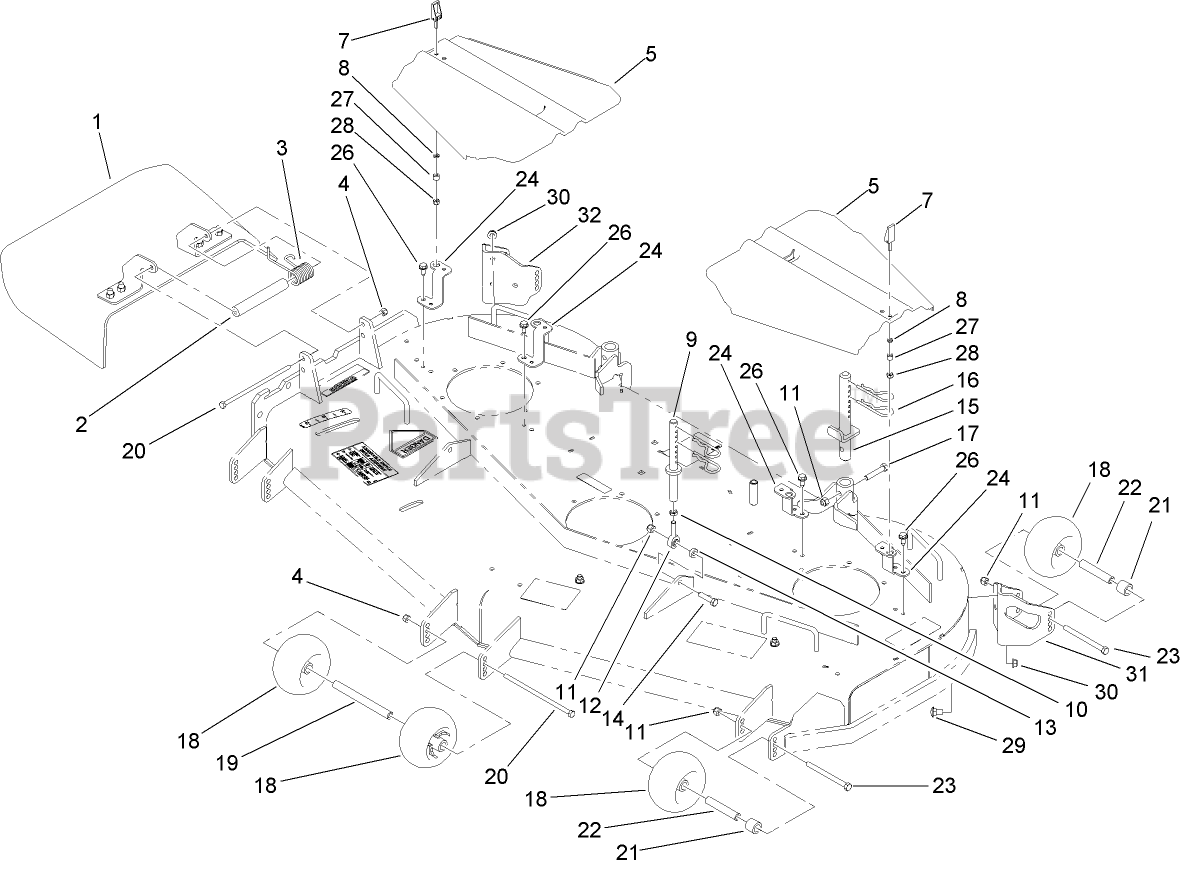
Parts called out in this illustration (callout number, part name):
1	DEFLECTOR ASM
2	SPACER
3	SPRING-TORSION
4	NUT-LOCK, NI
5	COVER-BELT
7	HANDLE-LATCH, SWELL
8	WASHER
9	FRONT PIN ASM
10	NUT-HJ
11	NUT-LOCK, NI
12	BALLJOINT
13	SPACER
14	SCREW-HH
15	REAR PIN ASM
16	PIN-HAIR
17	SCREW-HH
18	ROLLER-SCALP, ANTI
19	SPACER-WHEEL
20	SCREW-HH
21	TUBE-SPACER
22	TUBE-SPANNER
23	SCREW-HH
24	BRACKET-COVER
26	SCREW-HWHTF
27	BUSHING-LATCH, SWELL
28	NUT-LOCK, HH
29	SCREW-CARR
30	NUT-HF
31	BRACKET-ROLLER, LH
32	BRACKET-ROLLER, RH
